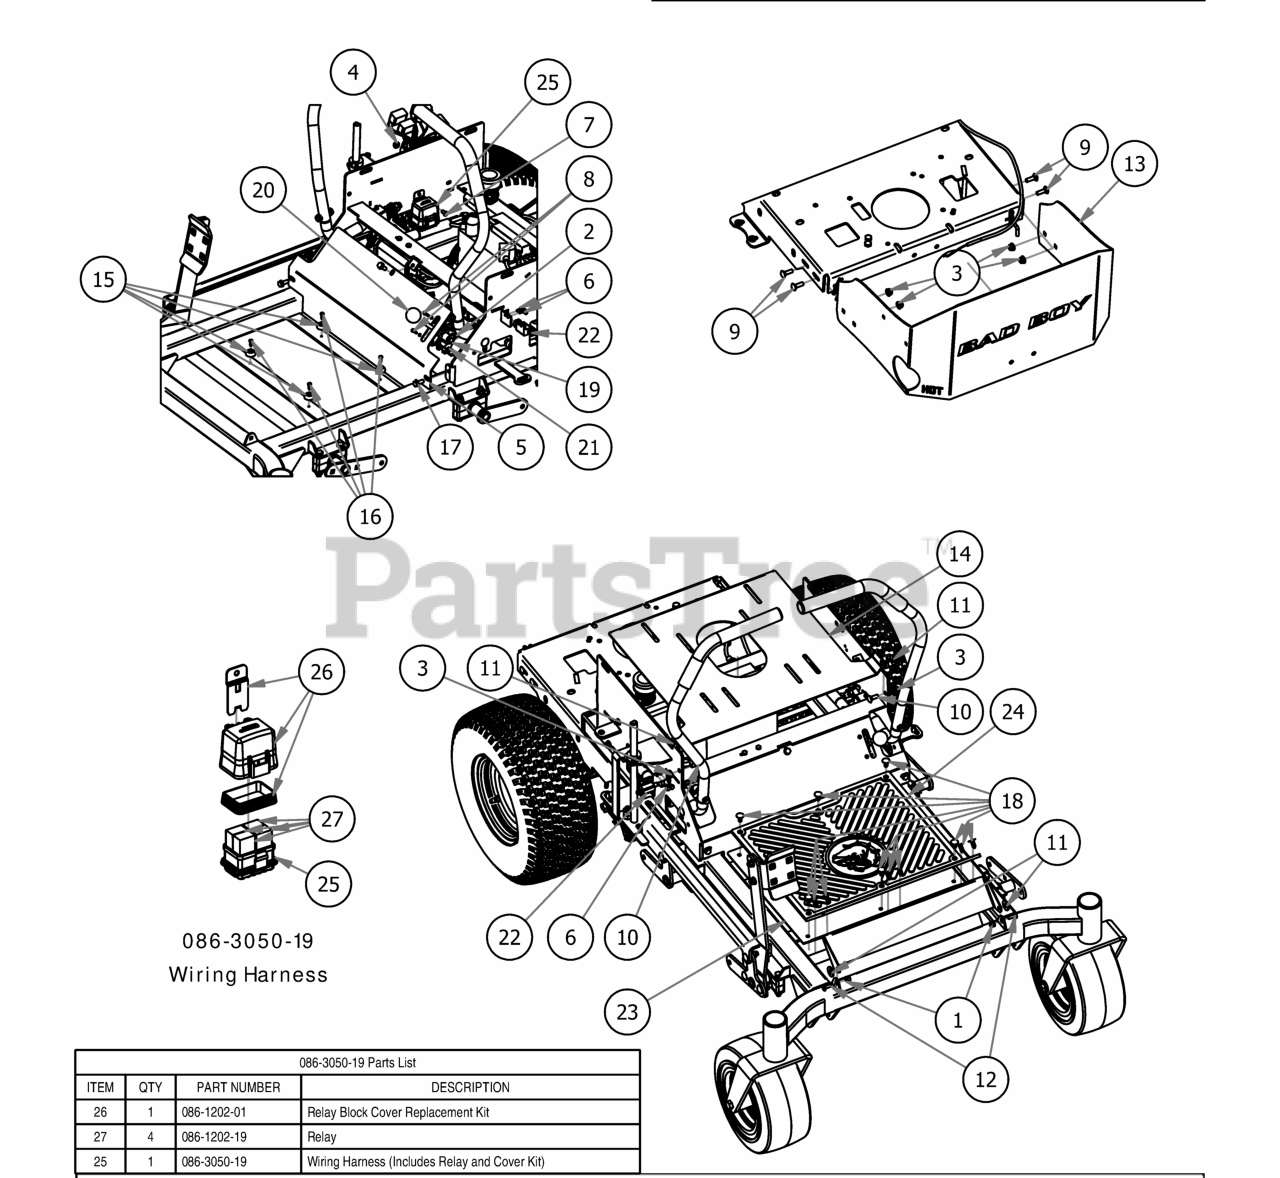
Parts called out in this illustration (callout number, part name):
1	1/4-20 Nylon Insert flange Nut
2	10-24 Nylon Insert Locknut Zinc Orange Nylon
3	5/16" Nylon Flange Nut
4	1/4-20 Hex Flange Nuts Zinc w/Serrations
5	2017 MZ Cooler Cover
6	12-24x 1/2 HWH Bolt
7	1/4" x 1/2" BS C/S 18-8 SS
8	10-24 X 5/8 BS Button Head Bolt
9	5/16" x 1" Carriage Bolt
10	5/16" x 7/8" Carriage Bolt
11	.360ID Plastic Washer
12	1/4" x 3/4" Carriage Bolt
13	2017 MZ Rear Plate
14	2017 MZ Seat Plate
15	Button Bumper
16	#10 x 1/2" Self Tapping Screw
17	5/16 x 3/4 washer head type F screw
18	Ratchet Fastener
19	Universal Throttle
20	Throttle Knob
21	MZ Brake Cable
22	Safety Switch
23	MZ/ZT 2017 Floorboard
24	2017 MZ/ZT Floor Mat
25	Wiring Harness
25	Wiring Harness (Includes Relay and Cover Kit)
26	Relay Block Cover Replacement Kit
